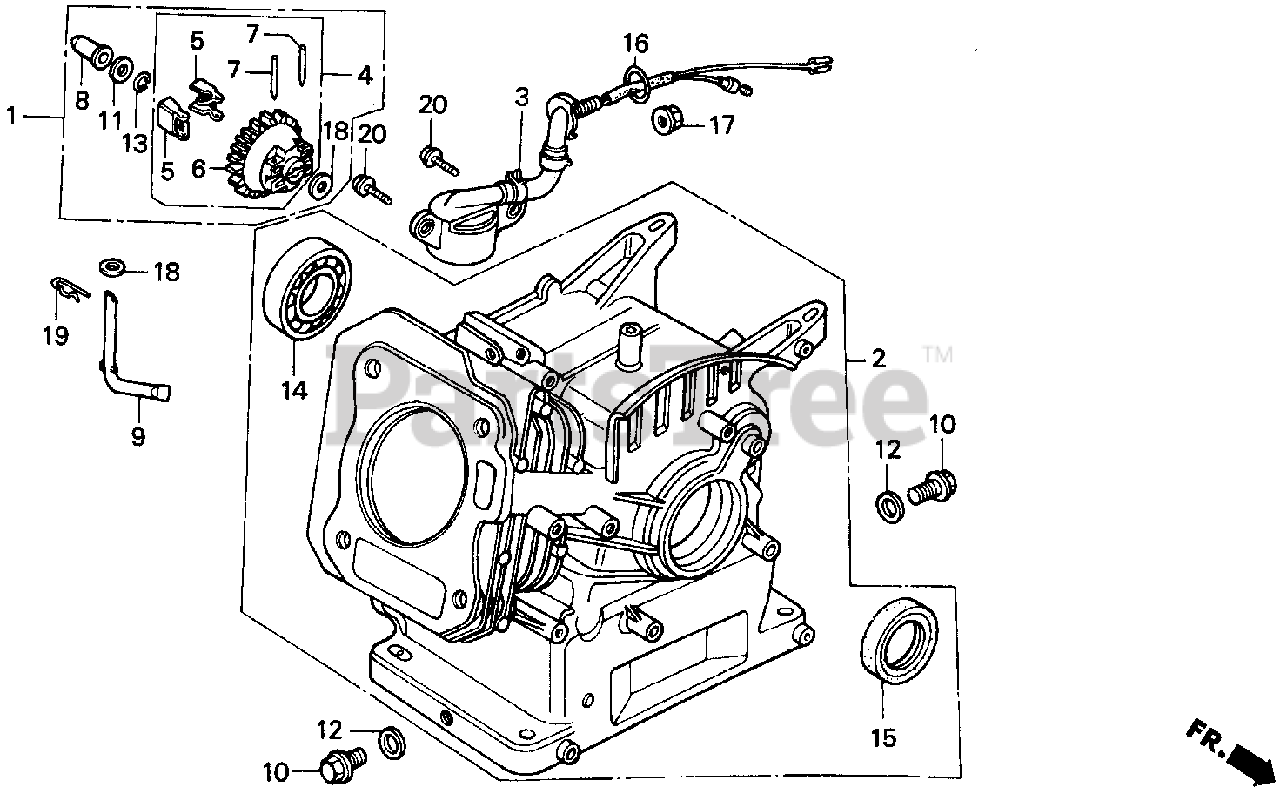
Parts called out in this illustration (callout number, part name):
2	CYLINDER ASSY. (811)
2	CYLINDER ASSY. (OIL ALERT)
3	SWITCH ASSY., OIL LEVEL
4	GOVERNOR ASSY.
5	WEIGHT, GOVERNOR
6	HOLDER, GOVERNOR WEIGHT
7	PIN, GOVERNOR WEIGHT
8	SLIDER, GOVERNOR
9	SHAFT, GOVERNOR ARM
10	BOLT, DRAIN PLUG
11	WASHER, THRUST (6MM)
12	WASHER, DRAIN PLUG (10.2MM)
13	CLIP, GOVERNOR HOLDER
14	BEARING, RADIAL BALL (6205)
15	OIL SEAL (25X41X6)
16	O-RING (13.5X1.5) (ARAI)
17	NUT, FLANGE (10MM)
18	WASHER, PLAIN (6MM)
19	PIN, LOCK (8MM)
20	BOLT, FLANGE (6X12)
